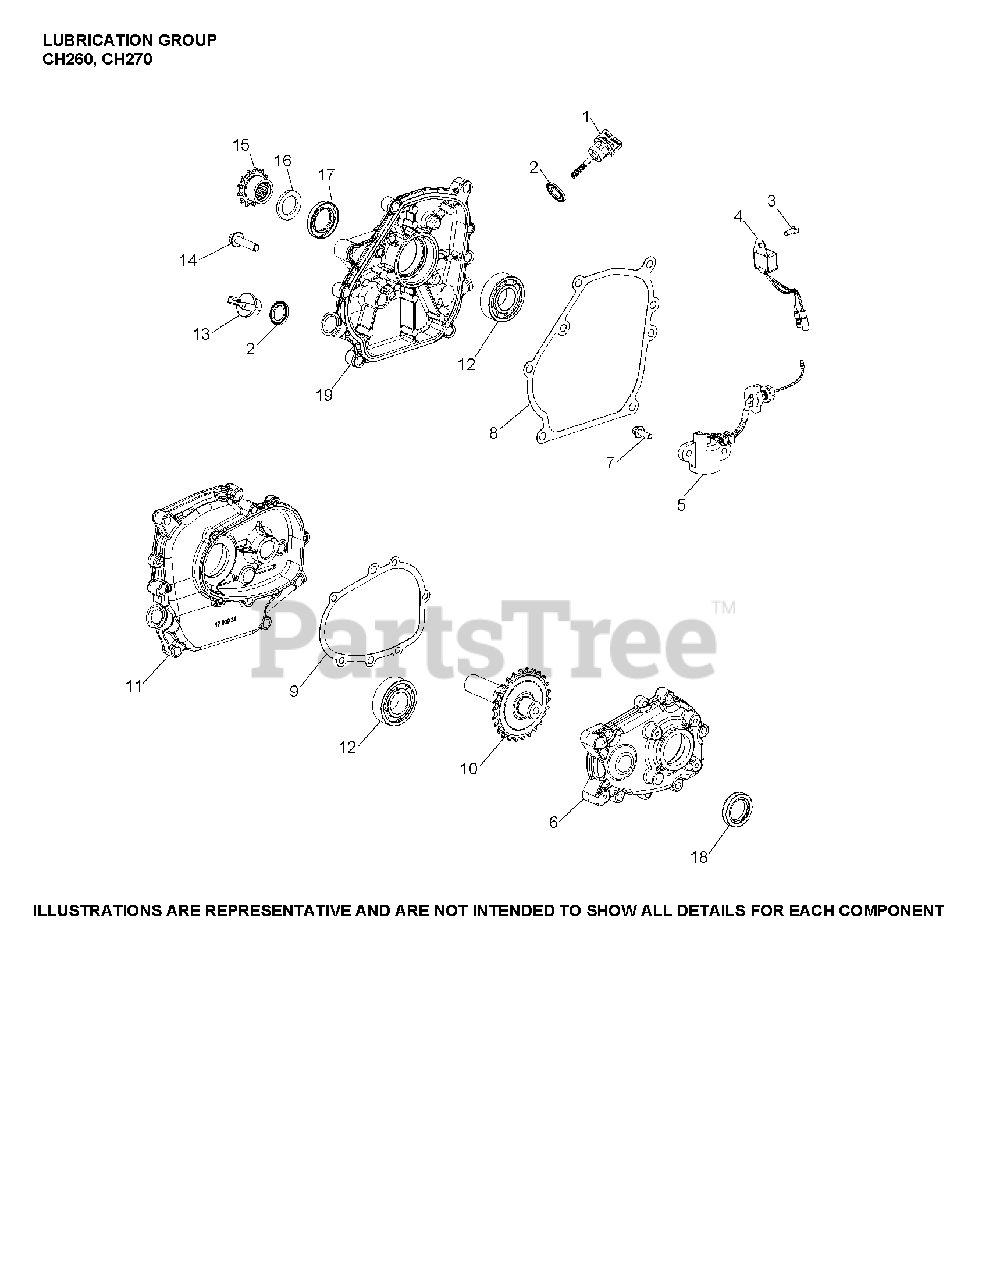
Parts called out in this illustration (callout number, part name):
1	DIPSTICK ASSEMBLY
2	SEAL, OIL
3	SCREW, HEX/PHILLIPS M5
4	CONTROL, OIL ALERT UNIT
5	SWITCH, OIL SENSOR ASSEMBLY
7	SCREW, M6 X18
8	GASKET, CLOSURE PLATE
12	BEARING, BALL
14	SCREW, CLOSURE PLATE
17	SEAL, CLOSURE PLATE
19	KIT, CLOSURE PLATE
